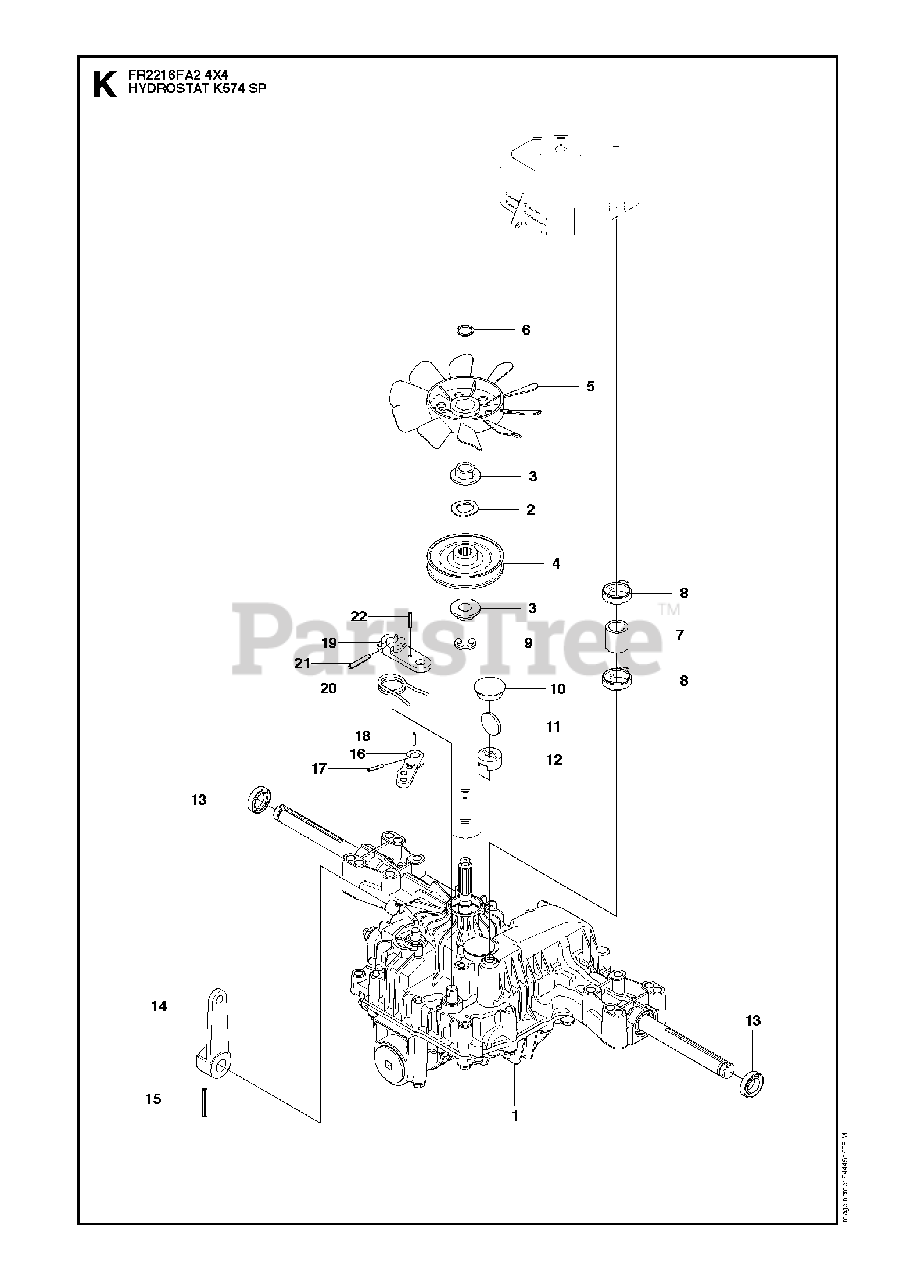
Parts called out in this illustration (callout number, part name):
1	HYDRAULMOTOR
2	WASHER **
5	FAN
6	RETAINING RING **
8	CLAMP
9	CLIP
10	PLUG
11	MAGNET
12	MAGNET HOLDER
13	SEALING
14	CONTROL LEVER
15	PIN
16	ARM
17	PIN
18	PIN
19	ARM
20	RETURN SPRING
21	PIN
22	PIN
